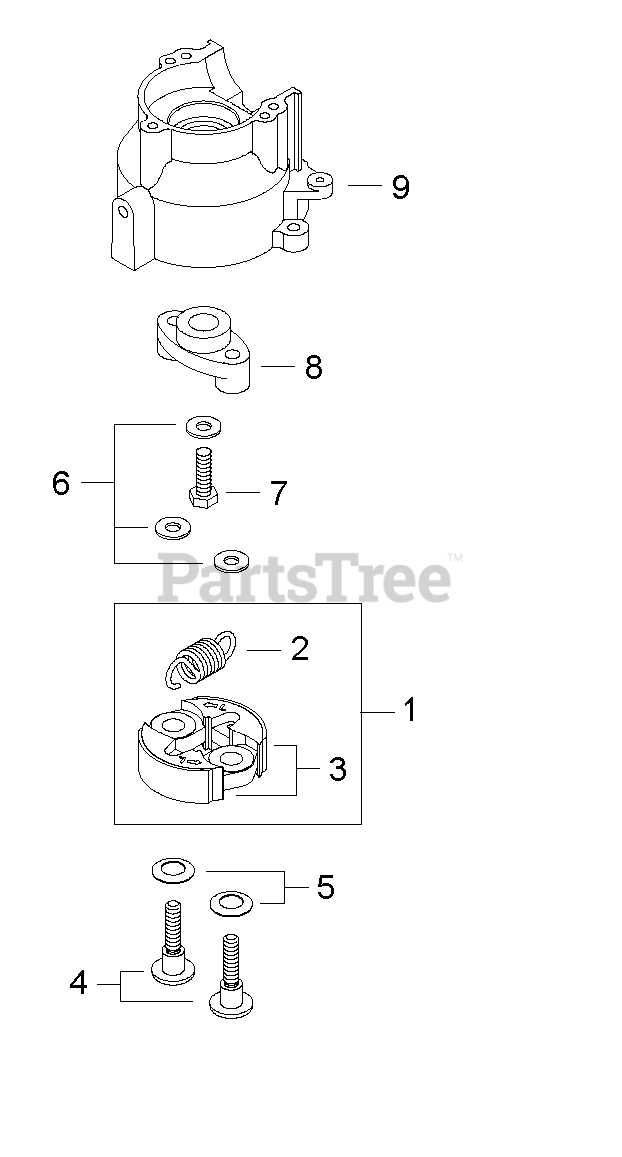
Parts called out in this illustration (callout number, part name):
1	CLUTCH ASSY
2	SPRING, CLUTCH
3	CLUTCH SHOE SET
4	BOLT, CLUTCH
5	WASHER - SPRING
6	WASHER - 6
7	SCREW - 6X18
8	HUB, CLUTCH
9	CRANKCASE ASSY
